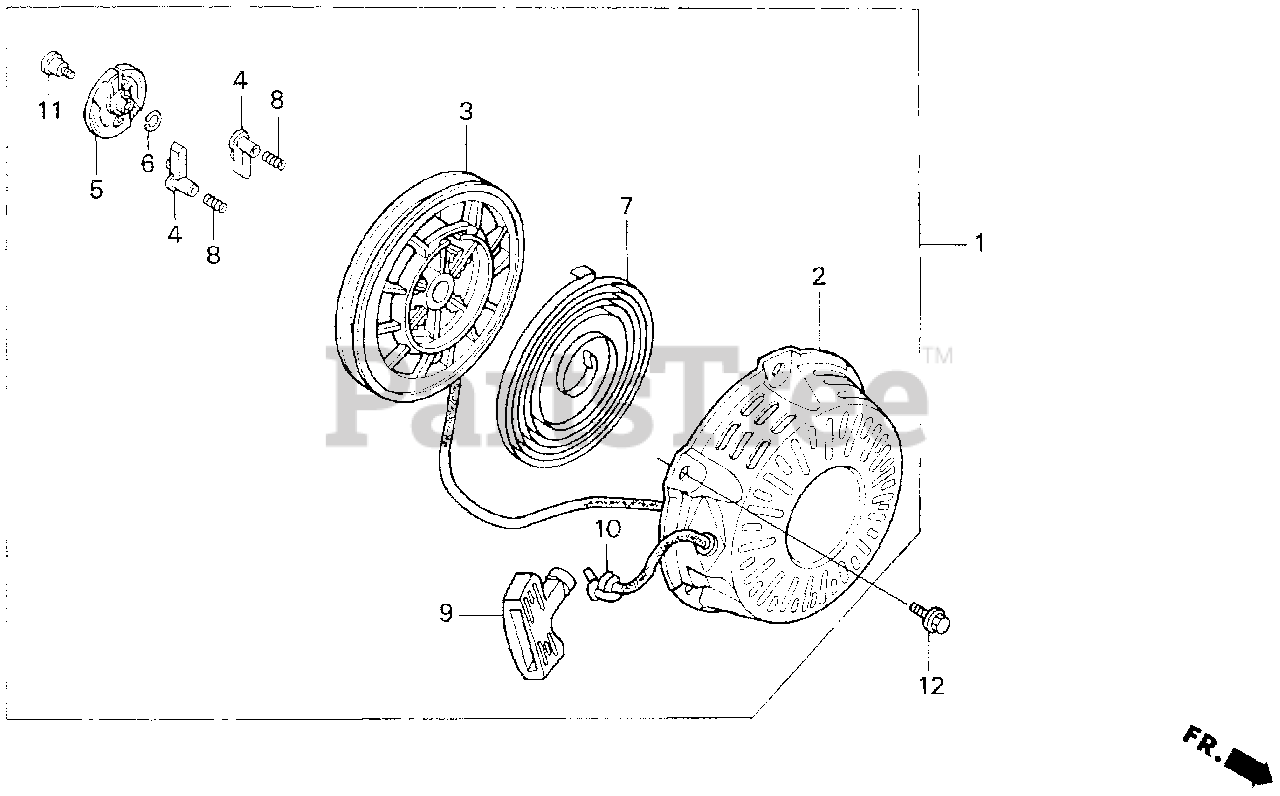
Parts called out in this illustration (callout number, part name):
1	STARTER ASSY., RECOIL *T68* (TSURUI BLUE)
1	STARTER ASSY., RECOIL *Y131* (LIGHTNING YELLOW)
2	CASE, RECOIL STARTER *T68* (TSURUI BLUE)
2	CASE, RECOIL STARTER
3	REEL, RECOIL STARTER
4	RATCHET, STARTER
5	GUIDE, RATCHET
6	SPRING, FRICTION
7	SPRING, RECOIL STARTER
8	SPRING, RETURN
9	KNOB, RECOIL STARTER
10	ROPE, RECOIL STARTER (NA USE ALT:08550-ZG921-11)
11	SCREW, SETTING
12	BOLT, FLANGE (6X10)
